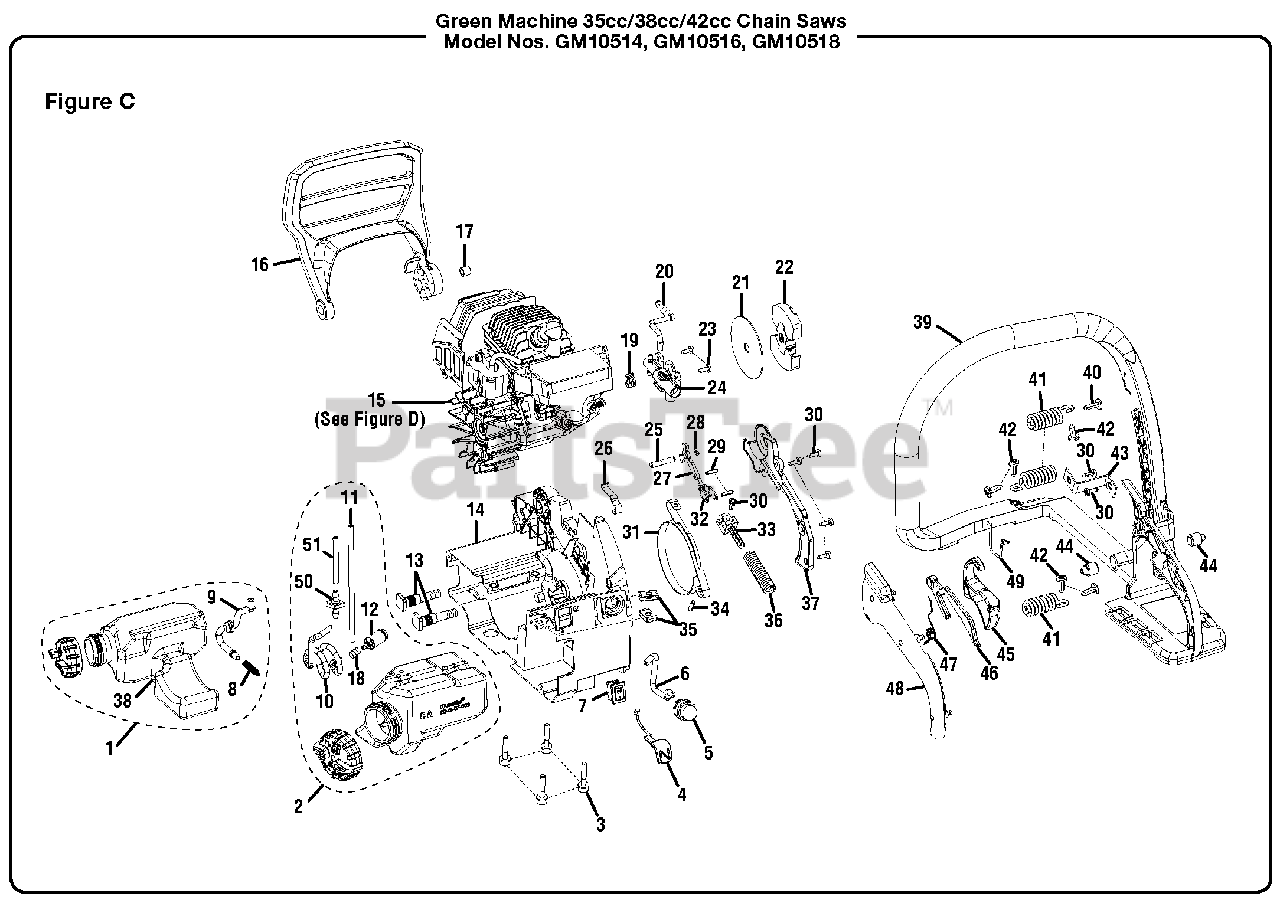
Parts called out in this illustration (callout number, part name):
1	Oil Tank & Cap Assembly (Inc. Key Nos. 8-9 and 38)
2	Fuel Tank & Cap Assembly (Inc. Key Nos. 10-12 and 18)
3	Screw (M5 x 28 mm)
4	Choke Lever
5	Primer Bulb
6	Primer Bulb Inlet Tube (73 mm)
8	Cone Spring
9	Oil Pump Inlet Tube
10	Fuel Line Inlet (Helical)
11	Fuel Line (220 mm)
12	Fuel Filter
13	Guide Bar Bolt (5/16-18)
14	Main Chassis
15	Engine Assembly
16	Front Hand Guard
17	Hand Guard Insert
18	Hose Clamp
19	Oil Pump Gear Spring
20	Oil Pump Outlet Tube
21	Thrust Washer
22	Clutch Assembly
23	Screw (M4 x 9.5 mm)
24	Oil Pump Assembly
25	Chain Brake Pin
27	Chain Break Pivot
28	E-Ring
29	Spring Pin
30	Screw (M4 x 12 mm)
31	Brake Band
32	Chain Brake Linkage
33	Spring Guide
34	Spring Pin
35	Speed Nut ("U"-Type)
36	Chain Brake Spring
37	Chain Brake Cover
39	Rear Handle
40	Screw (10-24 x 5/8 in.)
41	Isolator Spring
42	Screw (10-14 x 16 mm)
43	Anti-Vibe Strap
46	Lock-Out Lever
47	Trigger Return Spring
48	Rear Handle Cover
49	Throttle Rod
50	Fuel Fitting
51	Fuel Line Inlet (49 mm)
